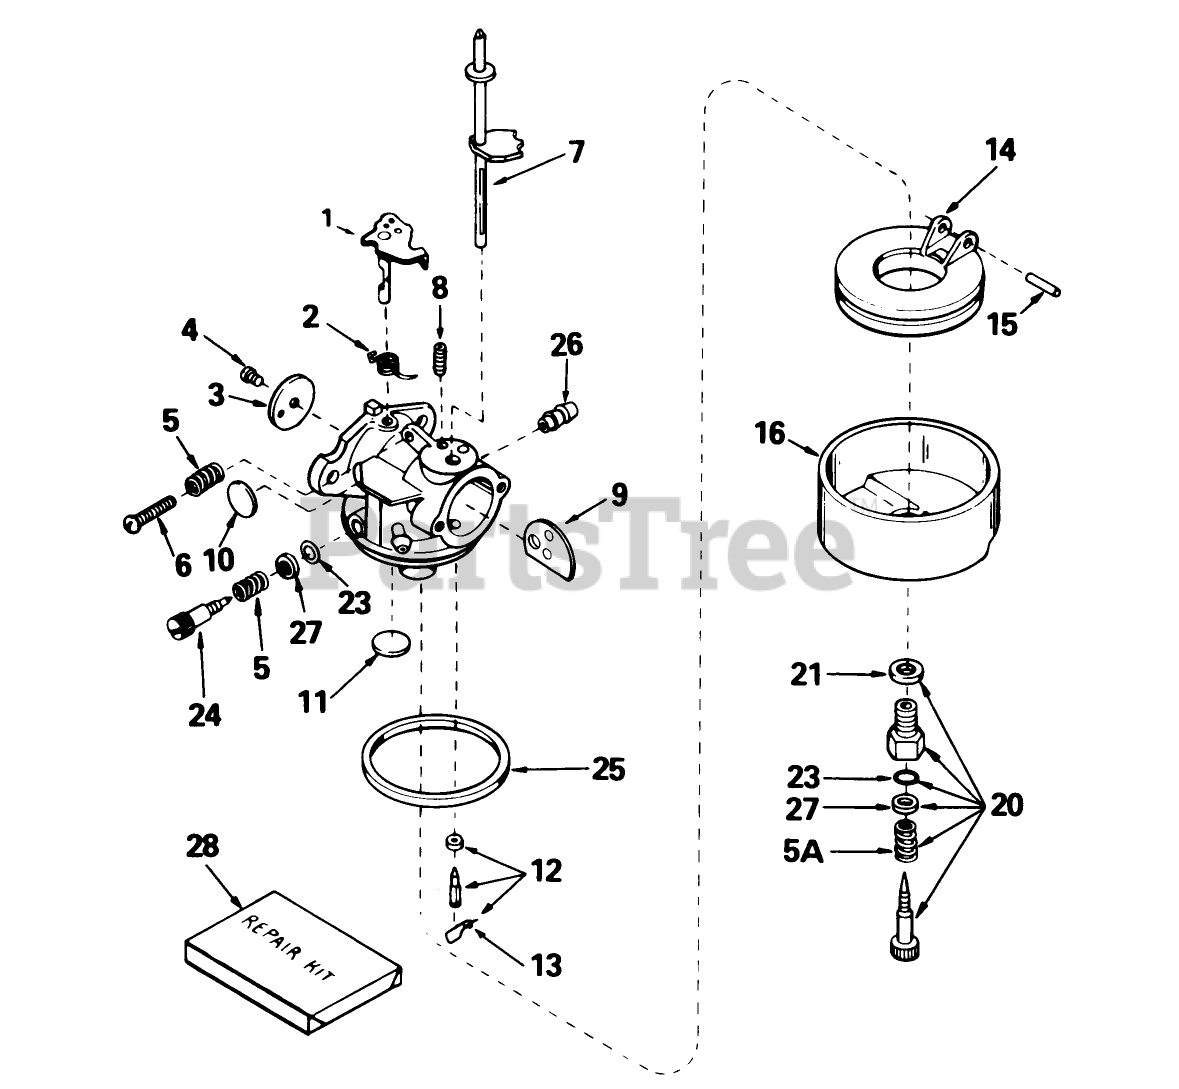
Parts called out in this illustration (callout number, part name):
1	Shaft/Lever-Throttle
2	Spring-Return, Throttle
3	Shutter-Throttle
4	Screw-Shutter
5	Spring-Tension
5A	Spring
6	Screw-Throttle Crack Screw / Idle Speed
7	Shaft-Choke
8	Spring-Positioning, Choke
9	Shutter-Choke
10	Plug-Welch, Idle Mixture Well
11	Plug-Welch, Atmospheric Vent
12	Inlet Needle, Seat Clip Assy. (Incl. No. 13)
13	Clip-Spring
14	Float
15	Shaft-Float
16	Bowl-Float (no drain)
20	Adjustment Screw Assy., Main (Incl. Nos. 5A, 21 23)
21	Washer-Bowl Nut
23	ORing
24	Screw, Idle Adj.
25	O Ring-Bowl, Float
26	Fitting-Fuel
27	Washer
28	Repair Kit (Incl. items marked *)
